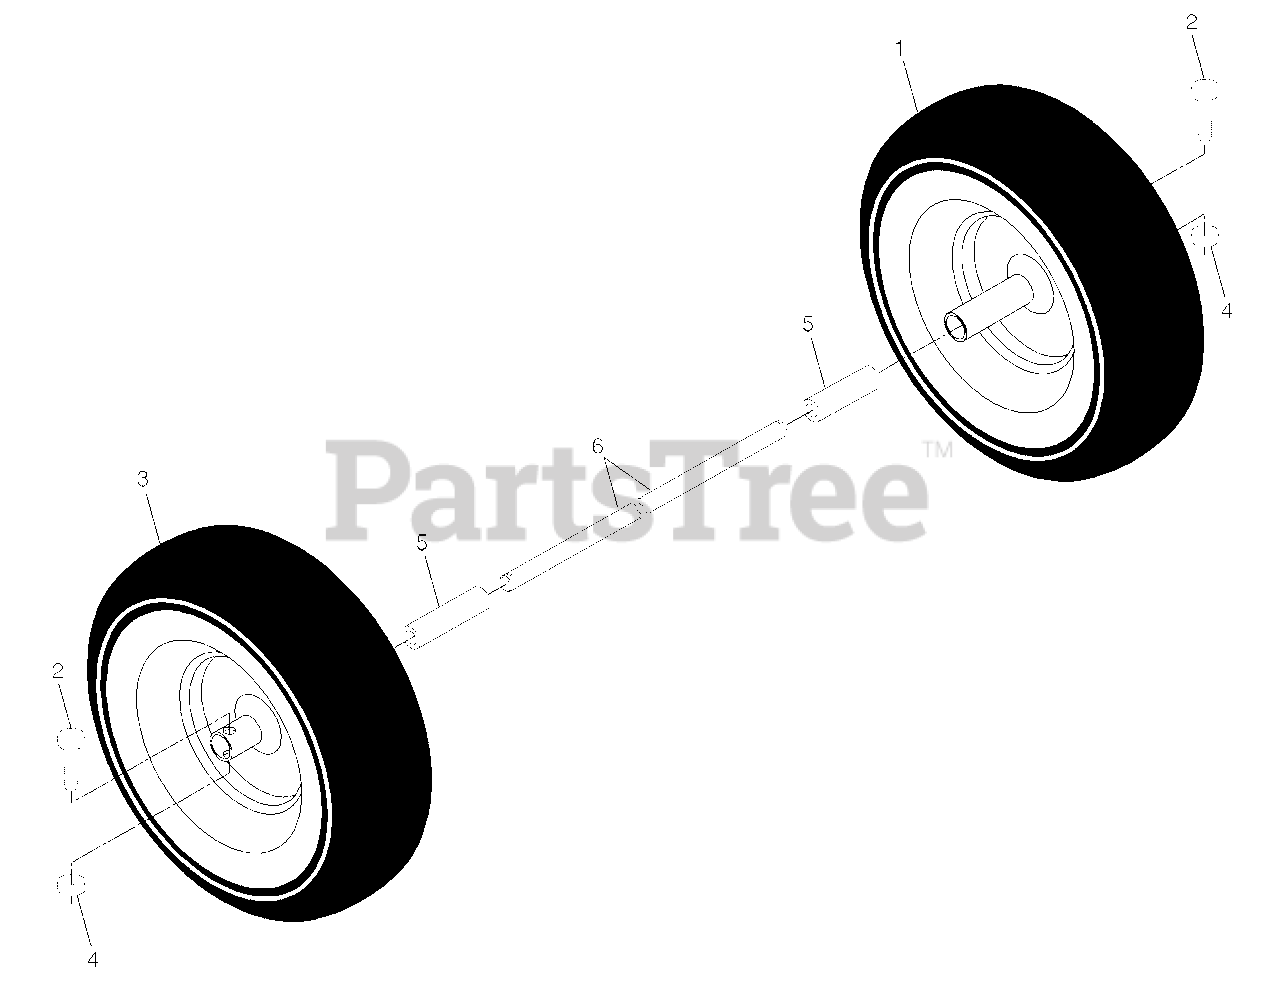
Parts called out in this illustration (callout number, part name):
1	Wheel Assembly, 16", Power Steering, LH
2	Screw, Hex Head
3	Wheel Assembly, 16", Power Steering, RH
4	Nut, Hex
6	Tube, Axle
